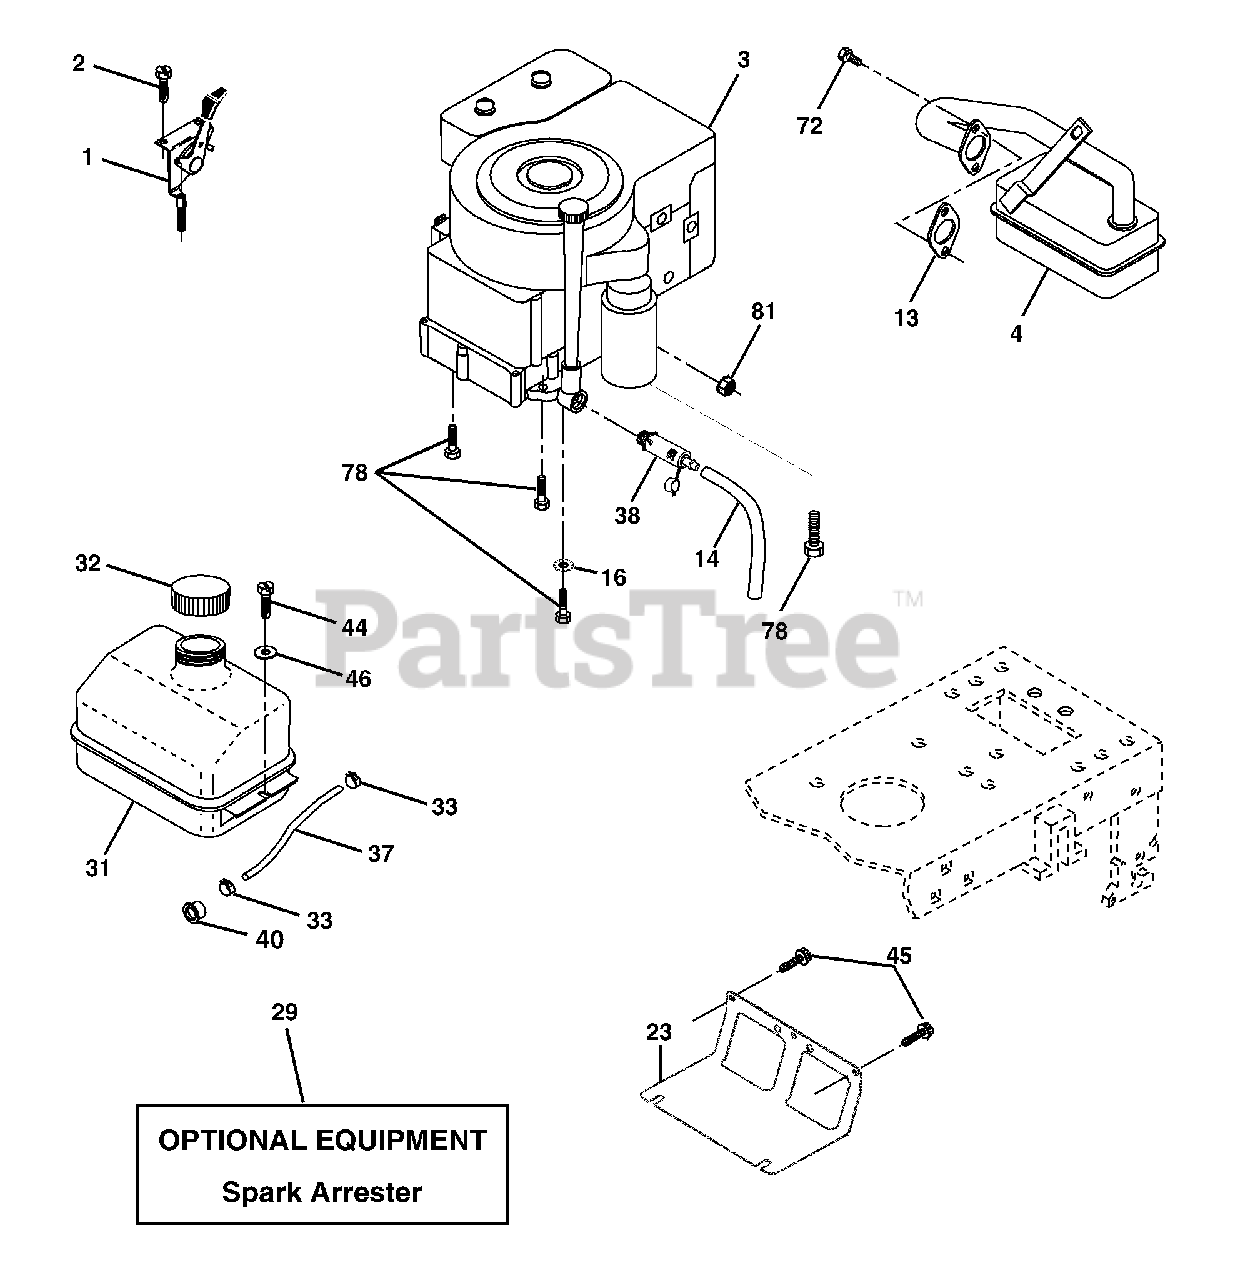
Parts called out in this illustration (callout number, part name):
1	Control Th/ch Flag
2	Screw Hex Thd Cut 1/4-20 x 1/2
4	Muffler Exhaust B&S
13	Gasket Eng 1 313 Id Tin Plated
14	Tube Drain Oil Easy
16	Washer Lock Ext Tooth 3/8
23	Shield BRN/DBR Guard
29	Kit Spark Arrestor (Flat Scrn)
31	Tank Fuel Front
32	Cap Asm Fuel
33	Clamp Hose
37	Line Fuel 20"
38	Plug Drain Oil
40	Bushing Snap Nyl Blk Fuel Line
44	Screw Thdrol 1/4-20 x 3/4
45	Screw Hex Wsh Thdrol 3/8-16
46	Washer 9/32 X 7/8 X 16 Ga.
72	Screw Socket Head 5/16-18 x 1
78	Screw 3/8-16 x 1-1/4
81	Nut Keps Hex 1/4-20 Unc
